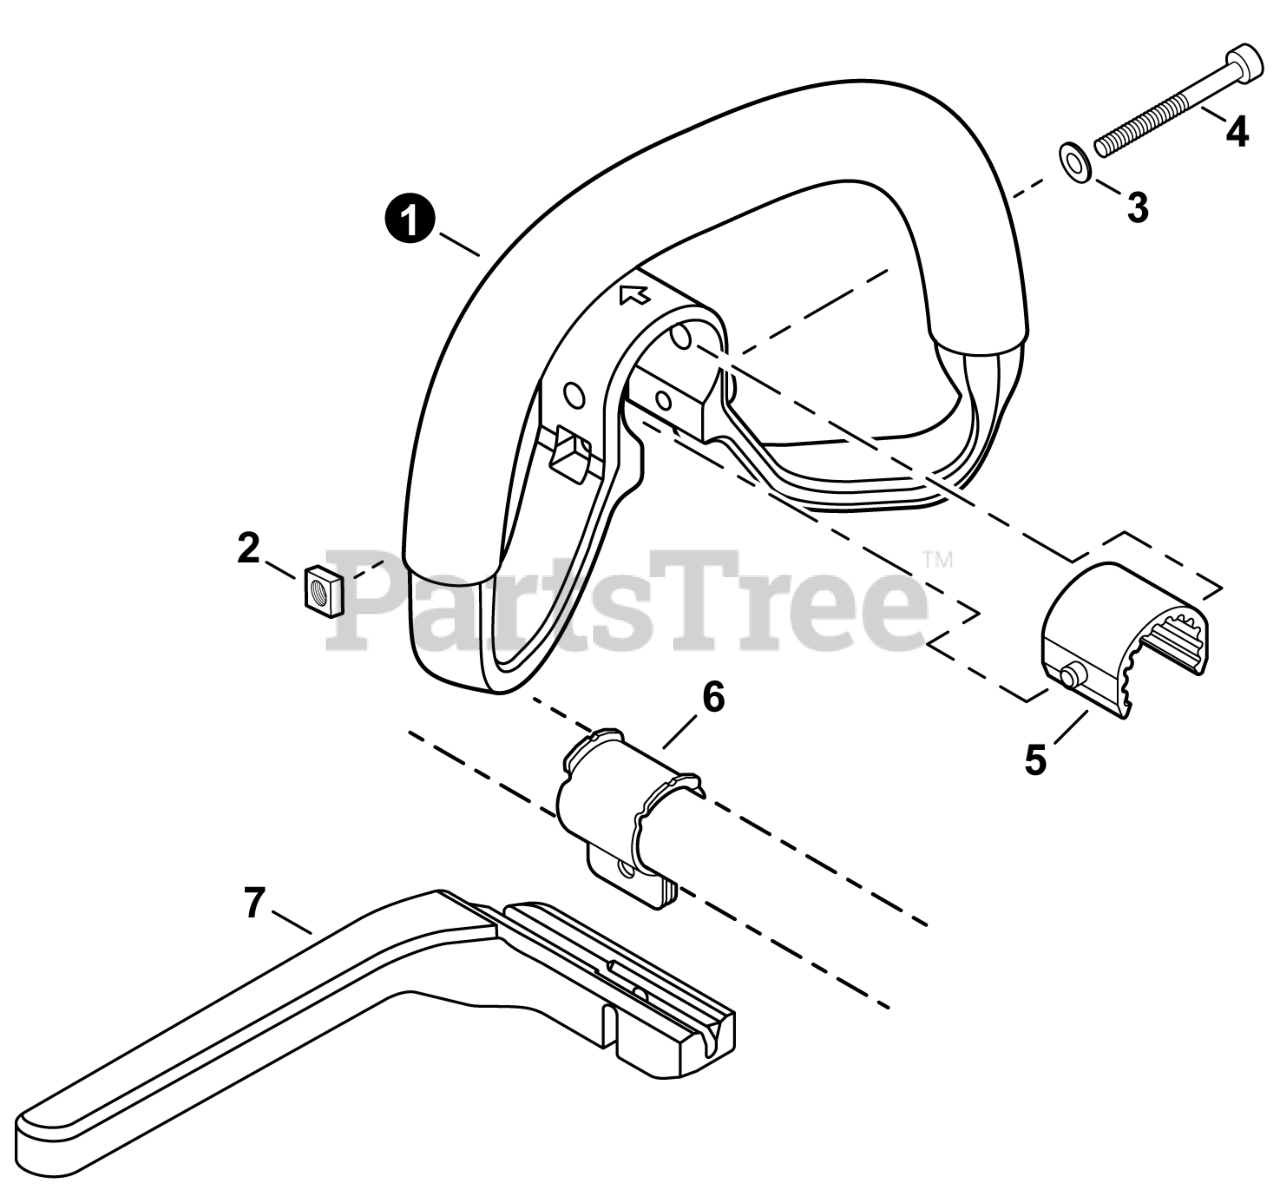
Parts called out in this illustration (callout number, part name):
1	HANDLE, SUPPORT
3	WASHER 5.5×12×0.8
4	BOLT, TORX 5×45
5	CUSHION
6	BRACKET, MOUNTING
7	BAR, BARRIER
